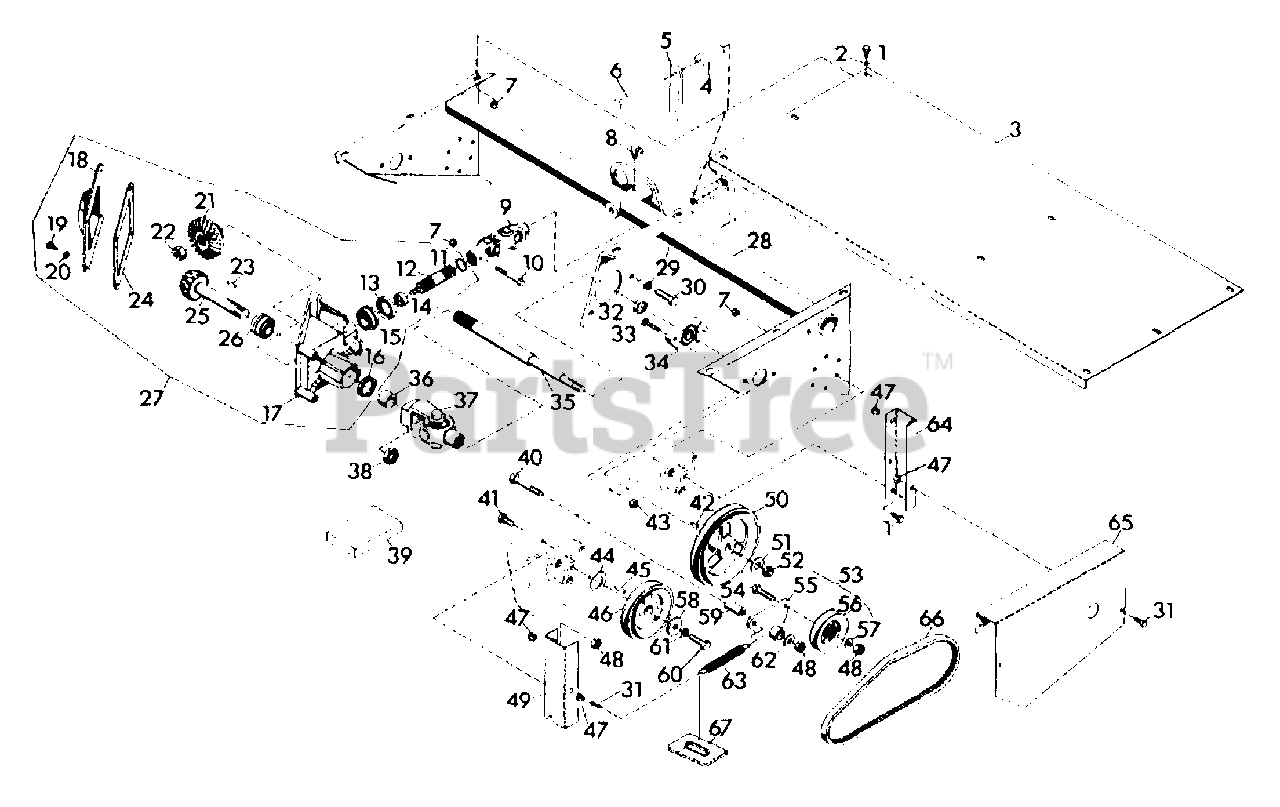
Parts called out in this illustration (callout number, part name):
1	Bolt-Hex .25-20 x .75 Grade 5
2	Washer-Flat-Steel .281 x .625 x .065
3	Shield
4	Bushing Sleeve .501 x 1.00 x 2.30
5	Strap, Locking
6	Bolt-Hex .50-13 x 4.50 Grade 5
7	Nut-Locking-Nylon .250-20 Grade 2
8	Fitting, Lube 90 Degree
9	Assembly, Double Joint
10	Bolt-Hex .25-20 x 2.00 Grade 5
11	Ring-Retaining 1.106 x .95
12	Shaft, Drive
13	Seal 1.250 x 1.983 x .250
14	Bushing, Flange 1.00 x 1.25 x 1.25
15	Bearing,-Assembly 1.000 x 1.980 x 1.243
16	Seal 1.250 x 1.691 x .310
17	Casting, Gear Box
18	Cover, Gear Housing
19	Bolt-Hex .25-20 x .50 Grade 5
20	Washer-Lock .250
21	Gear, Bevel
22	Nut-Locking-Nylon .75-10 Grade 2
23	Key Woodruff .19 x .63
24	Gasket, Gear Housing
25	Shaft, Gear Pinion
26	Bearing
27	Assembly, Drive
28	Weldment, Support
29	Washer-Lock .50
30	Bolt-Hex .50-13 x 1 Grade 5
31	Screw-Tapping .250-20 x .625
32	Bearing-Flange-Locking-Collar .75 x 1.85
33	Bolt-Round Head Square Neck .31-18 x 1.12
34	Bearing-Flange 2-Hole x .75
35	Shaft
36	Bushing, Sleeve .753 x 1.25 x 1.25
37	Joint, Universal
38	Nut-Locking-Nylon .75-10
39	Kit, Repair U-Joint
40	Bolt-Hex .38-16 x 2.50 Grade 5
41	Bolt-Hex .38-16 x .75 Grade 5
42	Key-Woodruff .19 x .75
43	Nut-Hex .312-18 Grade 2
44	Spacer, Pulley
45	Key-Square .248 x 1.0 x .248
46	Pulley-V 1.002 x 5.25
47	Grommet, Plastic
48	Nut-Locking-Nylon .375-16 Grade 2
49	Channel, Front
50	Sheave 7.25 x .656
51	Washer-Flat-Steel .656 x 1.312 x .095
52	Nut-Lock .625-18
53	Idler, Assembly
54	Bolt-Hex .38-16 x 1.625
55	Weldment, Arm Idler Pivot
56	Idler-Flat 3.437 x .376
57	Washer-Flat-Steel .406 x .812 x .065
58	Washer, Retaining
59	Bushing, Sleeve .406 x .750 x 1.70
60	Bolt-Hex .38-24 x 1.25 Grade 5
61	Washer-Locking-External .313 x .025
62	Washer-Flat-Steel .438 x 1.000 x .083
63	Spring-Tension .095 x .500 x 5.5
64	Channel, Rear
65	Cover, Belt
66	V-Belt 4L-Section 40.9 x .672
67	Spring Terminal
